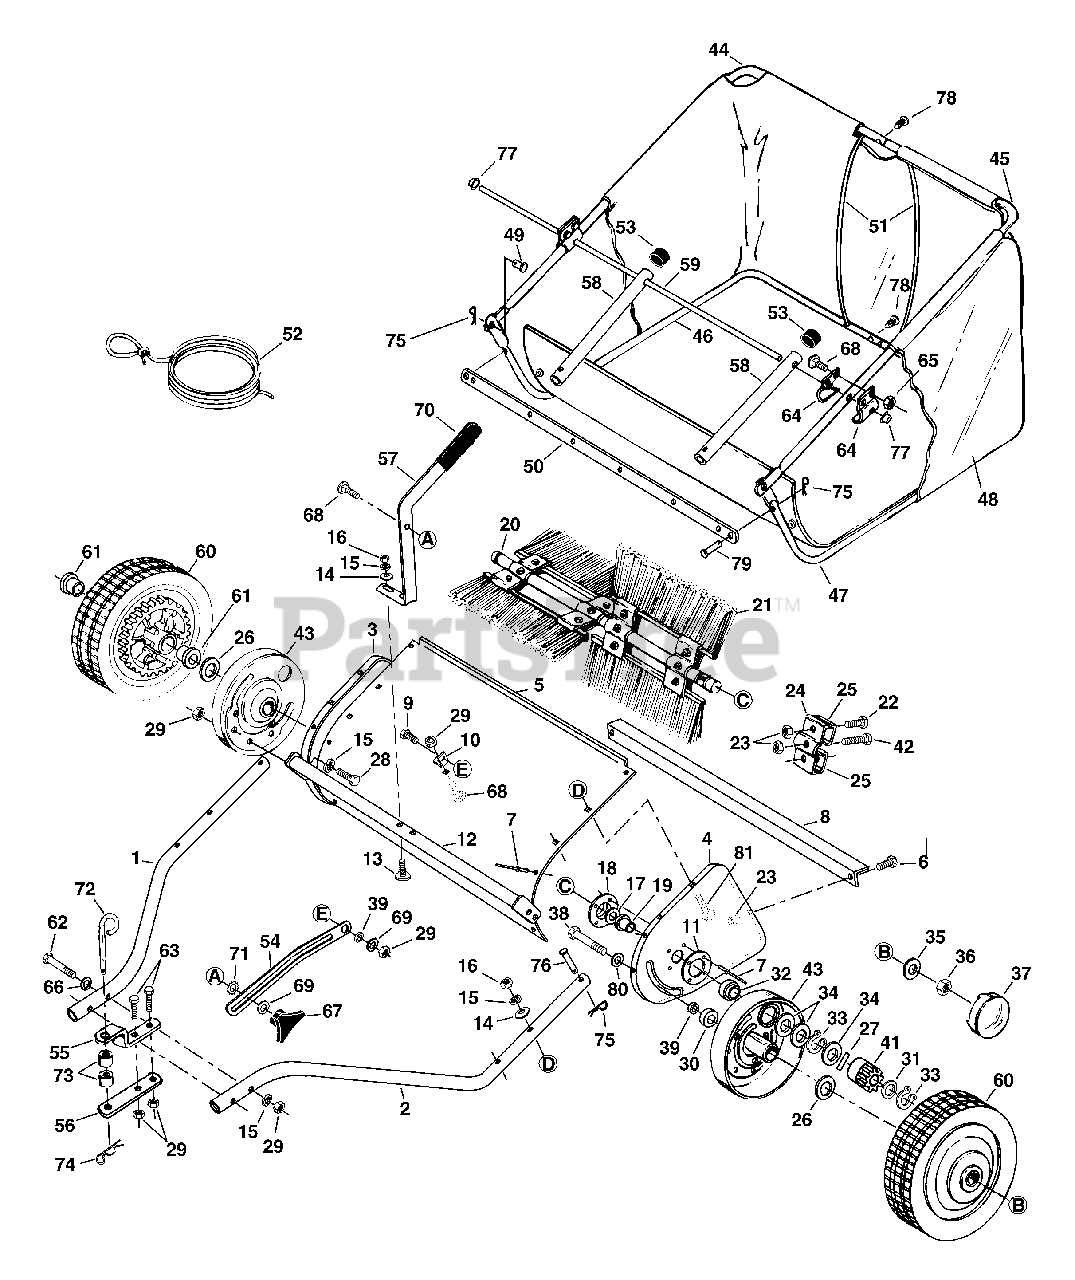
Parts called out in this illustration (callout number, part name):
1	Hitch Tube, R.H.
2	Hitch Tube, L.H.
3	End Plate, R.H.
4	End Plate, L.H.
6	Bolt Hex 1/4-20x1/2"
7	Pop Rivet
8	Brace, Rear Support
10	Bracket, Angle
11	Washer, Special
12	Height Adjust Tube Assy.
13	Bolt,Cvd. Hd. 5/16-18x1-5/8"
14	Washer, Bowed 1"x.32"x.06"
17	Washer, 5/8" SAE
18	Retainer, Dust Cover
19	Bushing, Brush Shaft
20	Brush Shaft
21	Brush, 46"
23	Nut, Hex Lock 1/4-20
24	Retainer, Brush (Double)
25	Retainer, Brush (Single)
26	Washer, 1-1/8"x.78"x.025"
29	Nut, Hex Lock 5/16-18
31	Washer, .894"x.598"x.025"
33	Ring, Retaining .594
34	Washer, Shim .025"
35	Washer, Flat .062"
38	Bolt, Hex 3/8-24x3-1/4"
39	Bushing Spacer
40	Gear, Pinion R.H. (N.S.)
41	Gear, Pinion L.H.
43	Assy, Dust Cover
44	Tube, Upper Hopper Frame R.H.
45	Tube, Upper Hopper Frame L.H.
46	Tube, Lower Hopper Frame R.H.
47	Tube, Lower Hopper Frame L.H.
48	Hopper Bag
49	Clevis Pin, 3/8"x1/2"
50	Strap, Bag Frame
51	Rod, Hopper Support
52	Hopper Rope
53	Cap, Vinyl
54	Strap, Height Adjustment
55	Bracket, Hitch
56	Bracket, Hitch (Straight)
57	Handle, Height Adjustment
58	Tube, Bag Arm
59	Rod, Hopper Bag Pivot
60	Wheel & Tire Assy. (w/Brgs.)
61	Wheel Bearings
64	Clamp Hopper Mount
65	Nut, Hex 5/16-18 (SEMS)
67	Knob, Wing 5/16-18
68	Bolt, Carriage 5/16-18x3/4"
69	Washer, 5/16" Std.
70	Grip, Height Adjust
71	Washer, Tooth Lock 5/16"
72	Pin, Hitch
73	Tube, Hitch Spacer
74	Hairpin Cotter, 1/8" #4
75	Hairpin Cotter, 3/32" #3
76	Pin, Clevis 1/4"x1-3/4"
77	Palnut, 3/8"
78	Plastic Plug
79	Clevis Pin, 1/4"x1-1/8"
80	Washer, 3/8" Std.
